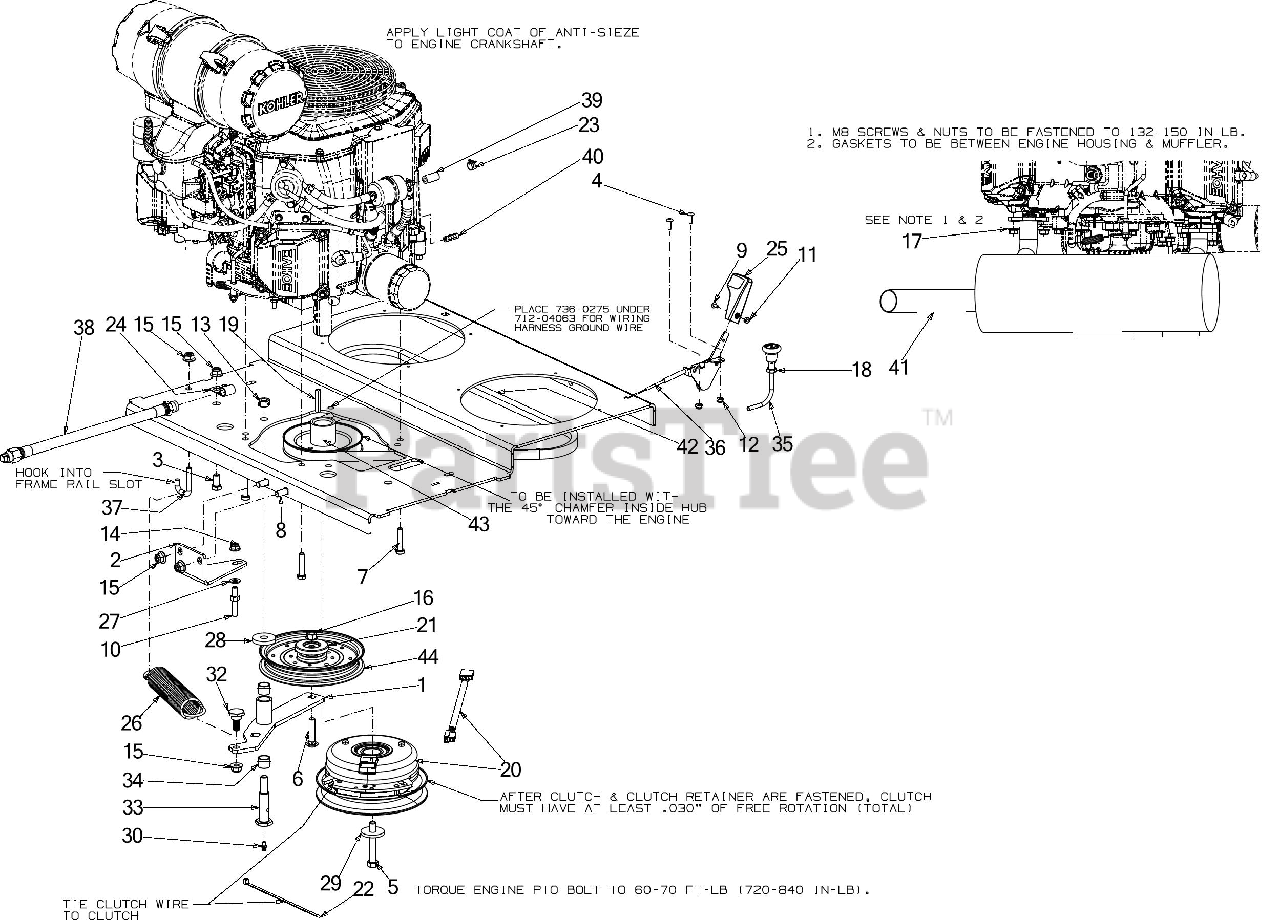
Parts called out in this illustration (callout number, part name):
1	TRANSMISSION IDLER BRACKET
2	RETAINER BRACKET
3	HEX SCREW 3/8-16 x .75
4	SCREW #10-24 x .62
5	SCREW 7/16-20:2.75 GR5
6	CARRIAGE BOLT 3/8-16 x 1.75 GR5
7	SCREW 5/16-18 x 1.5 LG
8	CARRIAGE BOLT 3/8-16 x 1.00 GR5
9	SCREW #8-32X.38 LG
11	HEX NUT 8-32
14	FLANGE LOCK NUT 5/16-18
16	HEX LOCK NUT
17	HEX FLANGE NUT
18	HEX JAM NUT 3/8X24
19	SQUARE KEY 1/4 x 1.50
20	ELECTRIC PTO CLUTCH
21	PULLEY CAP
22	7" CABLE TIE
24	J TYPE CLIP
25	THROTTLE CONTROL KNOB
26	EXTENSION SPRING
27	FLAT WASHER
28	FLAT WASHER 47 x 1.50 x .225
29	FLAT WASHER .45 x 1.5 x .172 HT
30	GREASE FITTING
32	SHOULDER SCREW .625 x .302 x 3/8-16
33	SHOULDER BOLT 7/16-14
34	SLEEVE BEARING
35	CHOKE CABLE
36	THROTTLE CABLE 42"
37	ROD SPRING HOOK
38	OIL DRAIN HOSE
39	FUEL HOSE LOW PERMEATION
40	VENT HOSE 3/16 ID
41	MUFFLER (KOHLER)
42	TRANSMISSION BELT 61.5
43	DRIVE PULLEY
44	IDLER PULLEY
